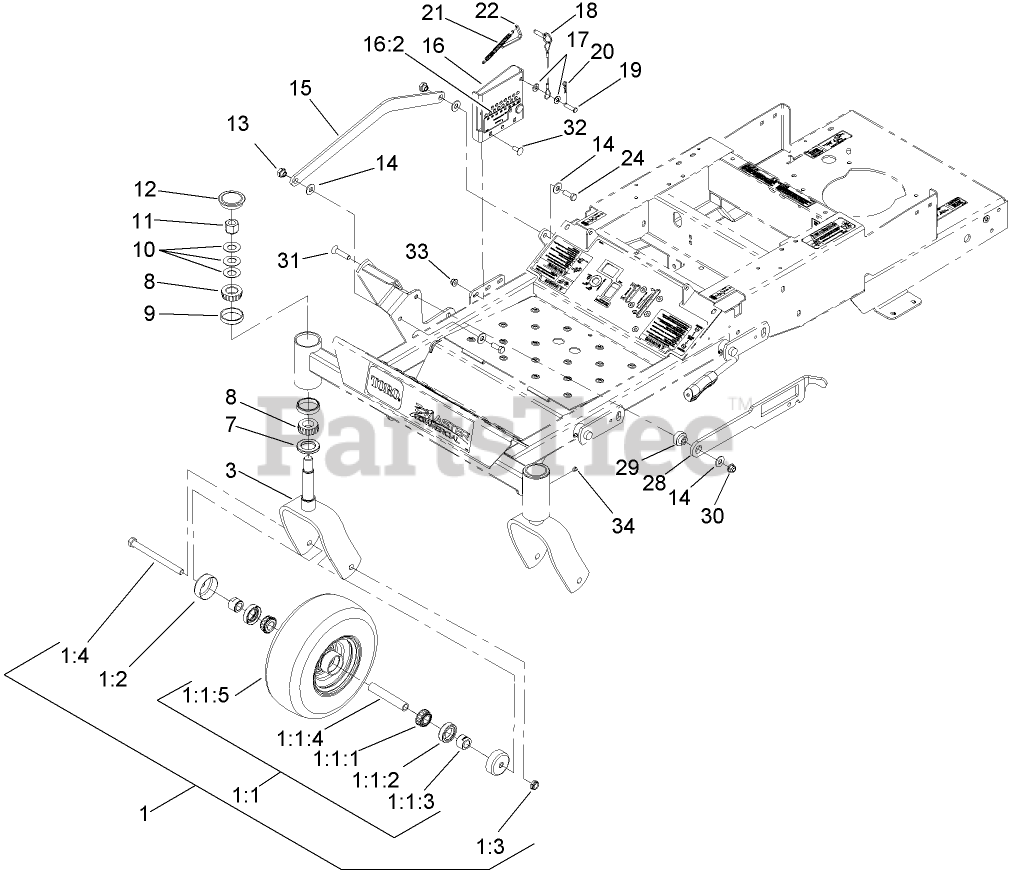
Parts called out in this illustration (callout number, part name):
1	WHEEL/TIRE AND BEARING ASM
1:1	WHEEL AND BEARING ASM
1:1:1	BEARING-CONE, TAPER
1:1:2	SEAL-CASTER
1:1:3	SPACER-NUT
1:1:4	AXLE-CASTER
1:1:5	WHEEL AND TIRE ASM
1:2	GUARD-SEAL
1:3	NUT-LOCK, NI
1:4	SCREW-HH
3	FORK-CASTER
7	SEAL-GREASE
8	BEARING-ROLLER, TAPERED
9	CUP-BEARING
10	WASHER-BELLVILLE
11	NUT-LOCK, NI
12	CAP-GREASE
13	NUT-SHOULDER
14	WASHER
15	LINK-CONTROL, DECK
16	HEIGHT ADJUST ASM
16:2	DECAL-HEIGHT, DECK
17	WASHER-SPRING
18	HEIGHT PIN W/LANYARD ASM
19	PIN-CLEVIS
20	PIN-COTTER
21	SPRING-ADJUST, HEIGHT
22	PAWL-CONTROL, HEIGHT
24	SCREW-HH
28	BAR-ADJUST, HEIGHT
29	BUSHING
30	NUT-HF, NI
31	SCREW-FH
32	SCREW-CARR
33	NUT-HF, NI
